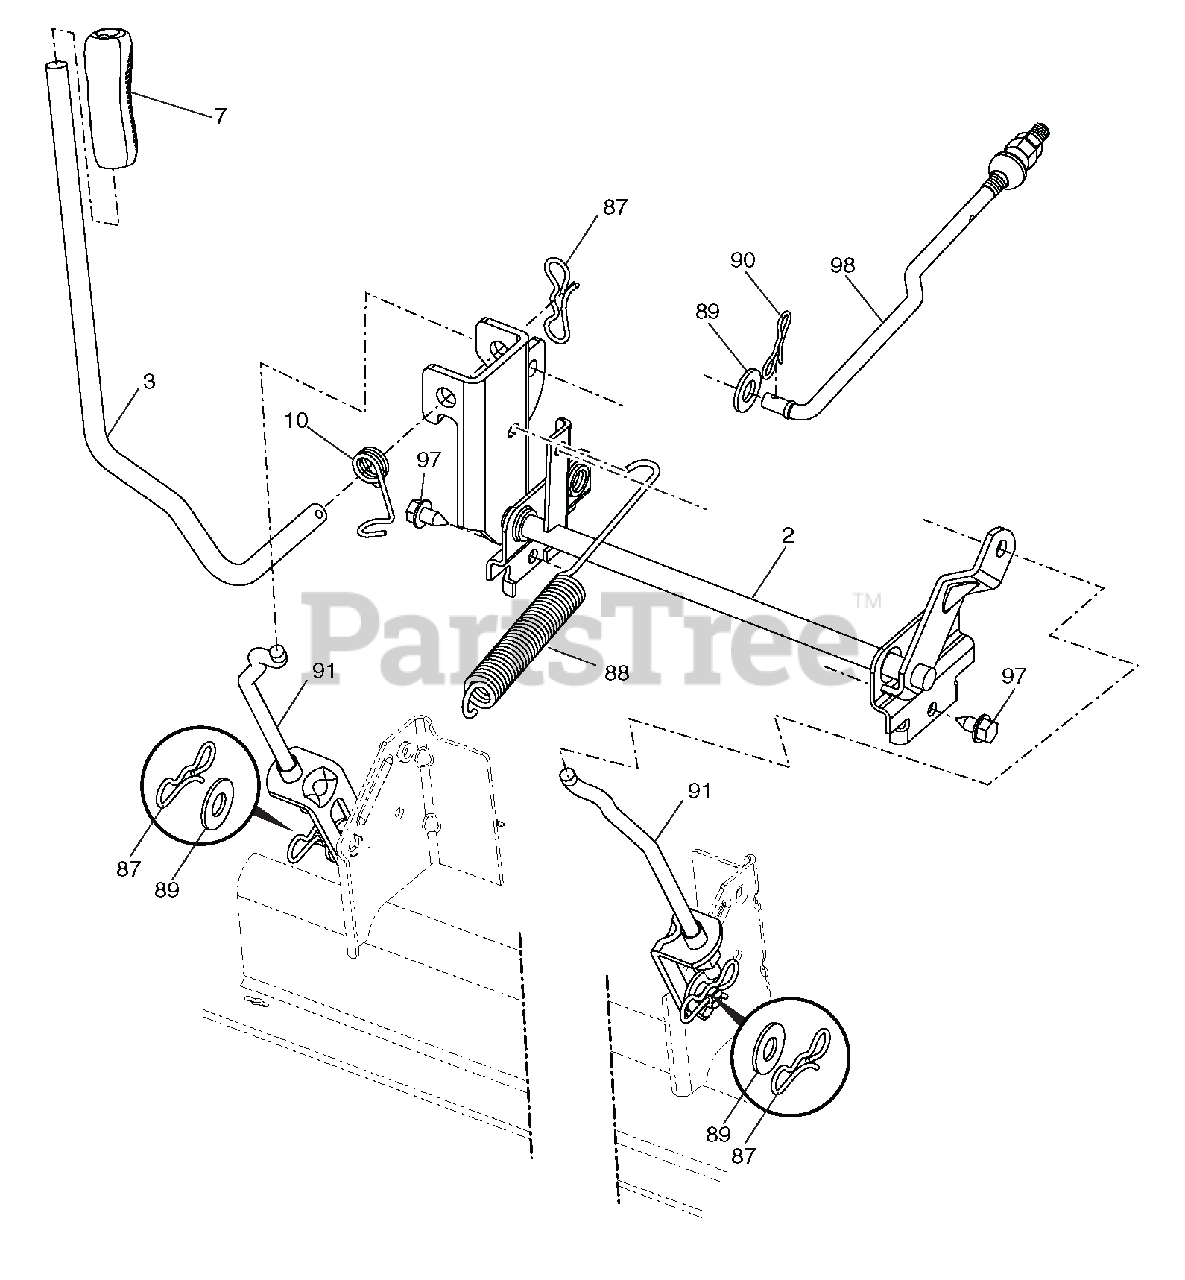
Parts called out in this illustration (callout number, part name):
2	SHAFT ASM., LIFT
3	LEVER.LIFT.HANDLE.LT
7	GRIP LEVER 5625 LD BLACK 428
10	SPRING.TORSION.HANDLE.LIFT
87	PIN.COTTER.7/16.BOW TIE LOCK
88	SPRING.LIFT ASSIST
89	WASHER.CLEAR ZINC
90	PIN.COTTER.5/16.BOW TIE LOCK
91	LINK.LIFT.SUSP.MOWER.REAR
97	SCREW.HEXWSH THDR3/8-16X3/4.BL
98	LINK.LIFT.SUSP.MOWER.FRONT
